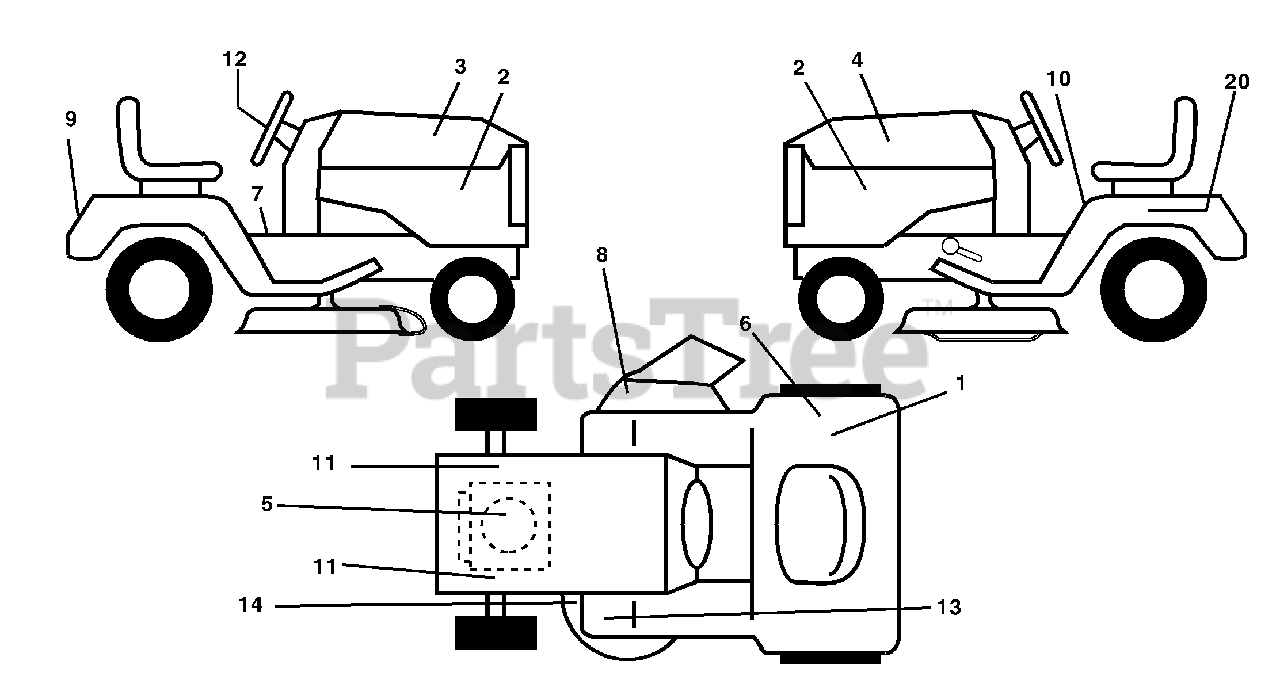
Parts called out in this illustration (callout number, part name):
1	Decal 100 DBA
2	Decal Panel Side B&S Logo
3	Decal Hood RH
4	Decal Hood LH
5	Decal HP Engine
6	Decal Euro Stand CE
7	Decal Saddle Brake
8	Decal Mower Cutfinger Symbol
9	Decal Fender Husq
10	Decal Read Owner's Manual Syms
11	Decal Chassis Hot Muffler
12	Decal Wheel Steering
13	Decal Brake/Clutch Symbol LT
14	Decal V-Belt Schematic
20	Decal Bat Dan/Psn
20	Decal Drawbar Load Limit
20	Decal By-Pass Lt Hydro
